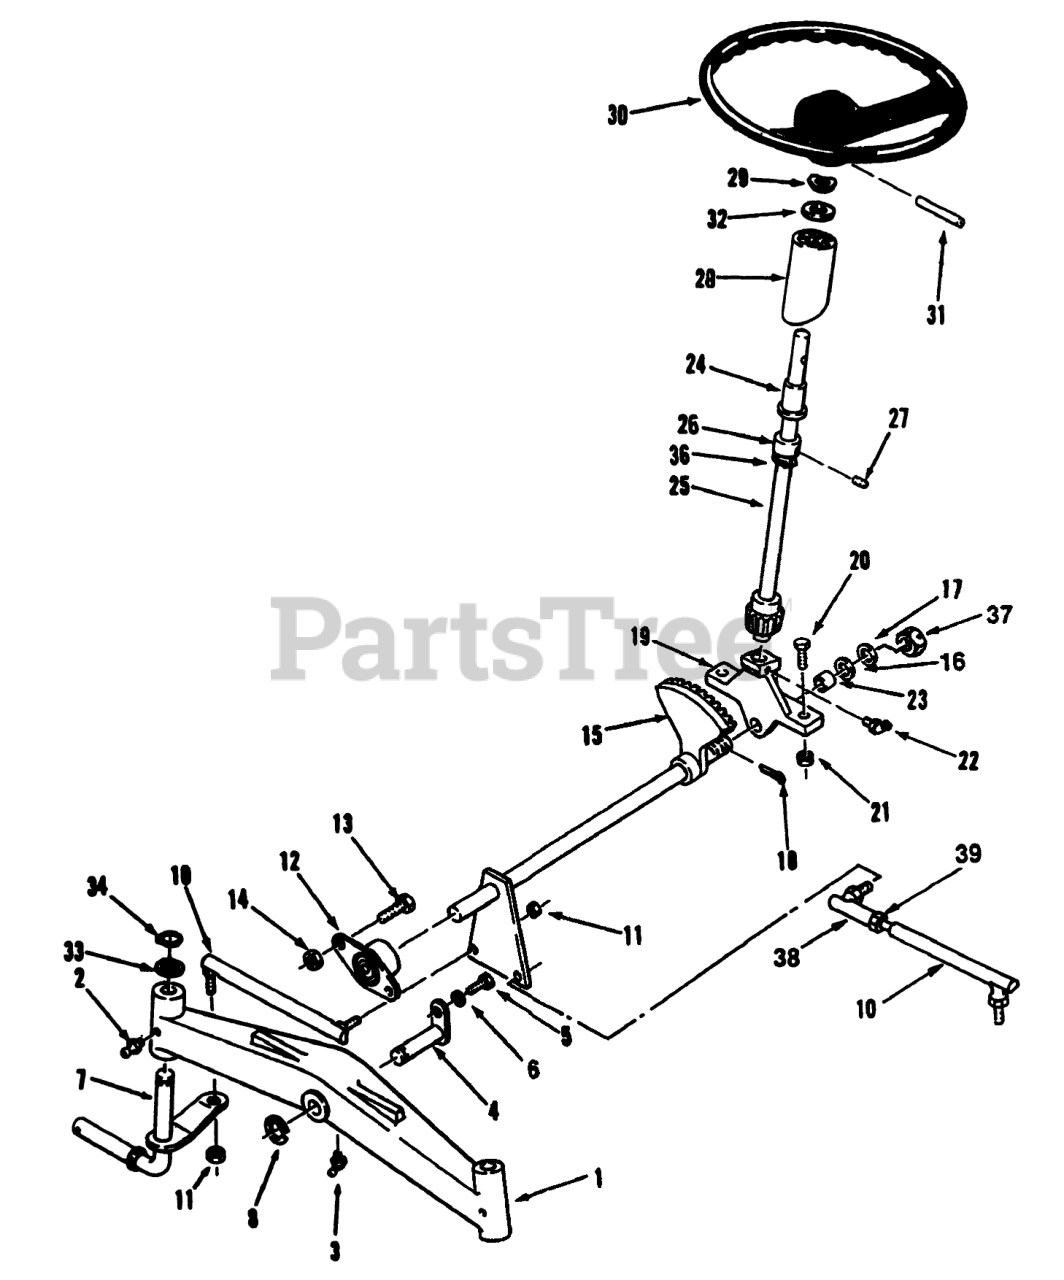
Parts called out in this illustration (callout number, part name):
1	AXLE-FRONT
2	Zerk
3	FITTING-GREASE
4	PIN AND PLATE ASM
5	SCREW-HH
6	WASHER-LOCK
7	LH SPINDLE ASM
8	E-RING
10	Tie Rod (Includes Item 38)
11	Nut
12	BEARING-FLANGED
13	SCREW-HH
14	NUT-LOCK, NI
15	Shaft
16	WASHER-SHIM
17	WASHER
18	PIN-COTTER
19	Support
20	SCREW-HH
21	NUT-HEX
22	FITTING-GREASE
23	BEARING-BRONZE
24	BEARING-FLANGED
25	WLDMT-UPPER SHAFT R
26	COLLAR
27	SCREW-HSH
28	TUBE-STEERING
29	WASHER-BOWED
30	Steering Wheel
31	PIN-ROLL
32	WASHER-FLAT
33	WASHER
34	RING-RETAINING
36	RING-RETAINING
37	NUT-HEX, SLOTTED
38	BALL-JOINT
39	NUT-6
